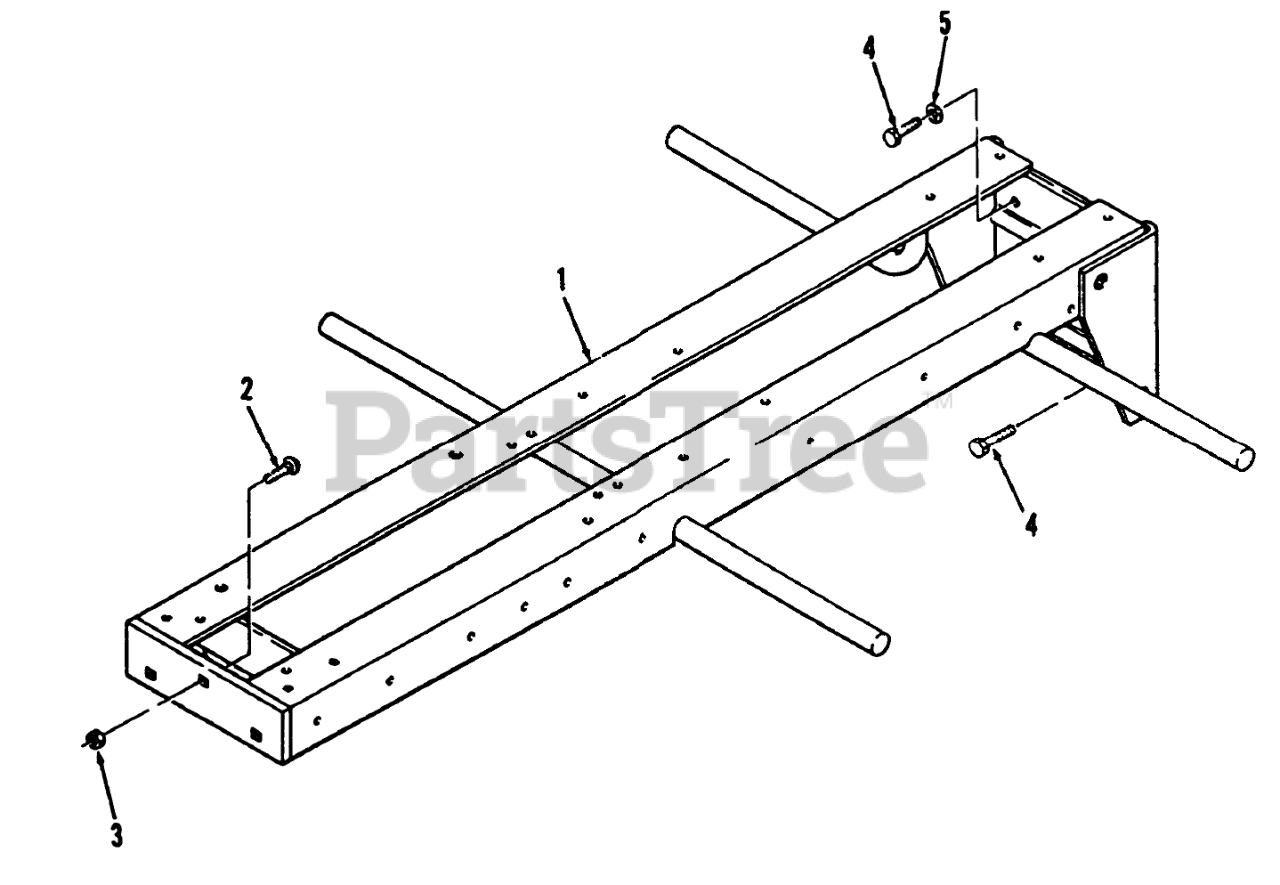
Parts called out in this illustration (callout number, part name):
1	WLDMT-FRAME R
2	BOLT-CARR
3	NUT-LOCK, NI
4	SCREW-HH
5	Washer-Lock 3/8
